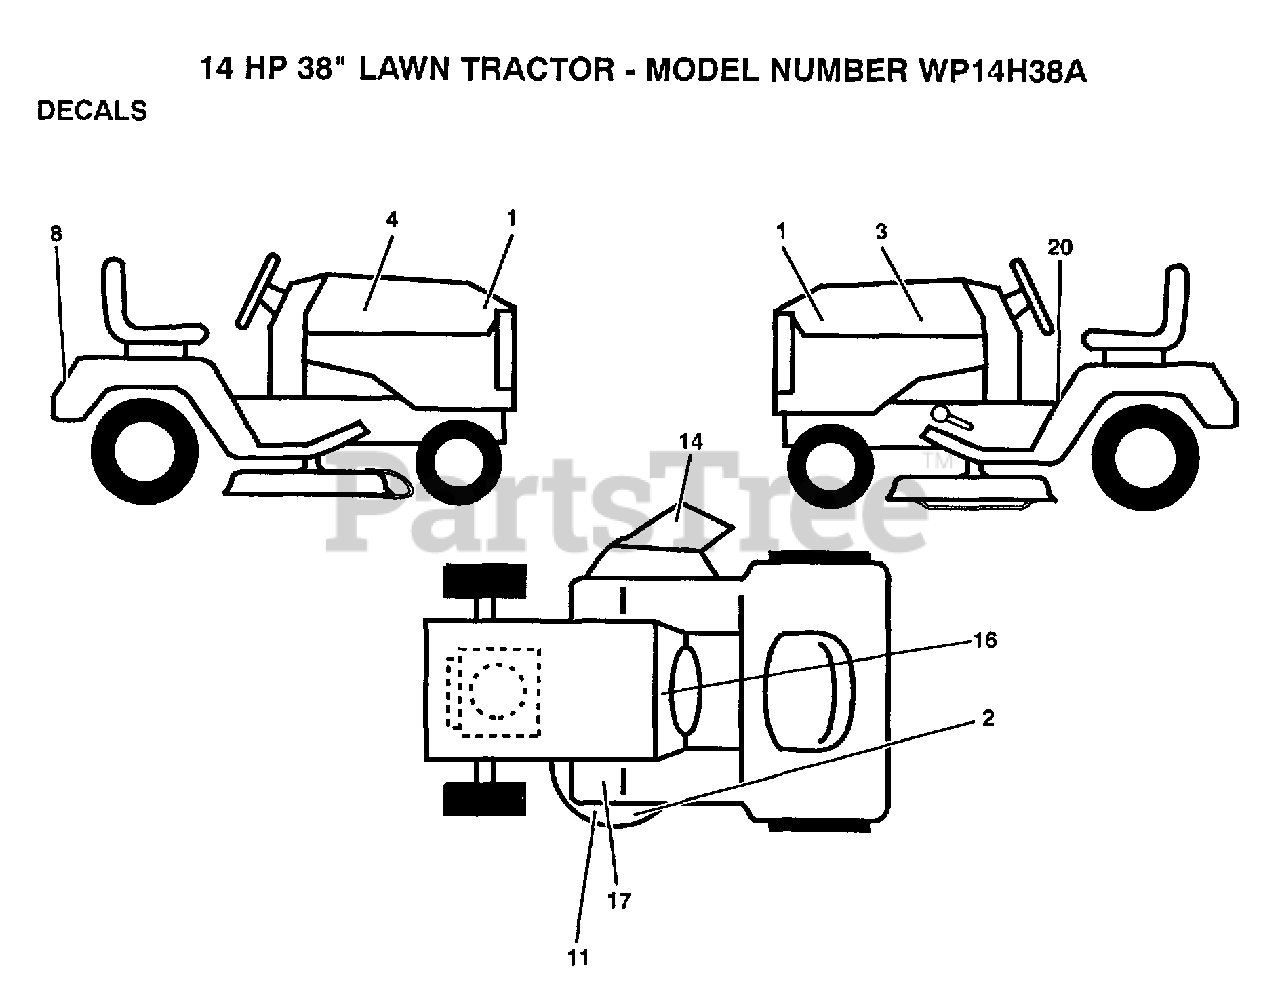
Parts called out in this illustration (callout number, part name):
2	"DECAL,ENVIRO DECK"
3	DECAL.HOOD.LH
4	DECAL.HOOD.RH
8	DECAL, LOGO, FENDER
11	DECAL INSTRUCTION CAUTION
14	DECAL WARING
20	DECAL
